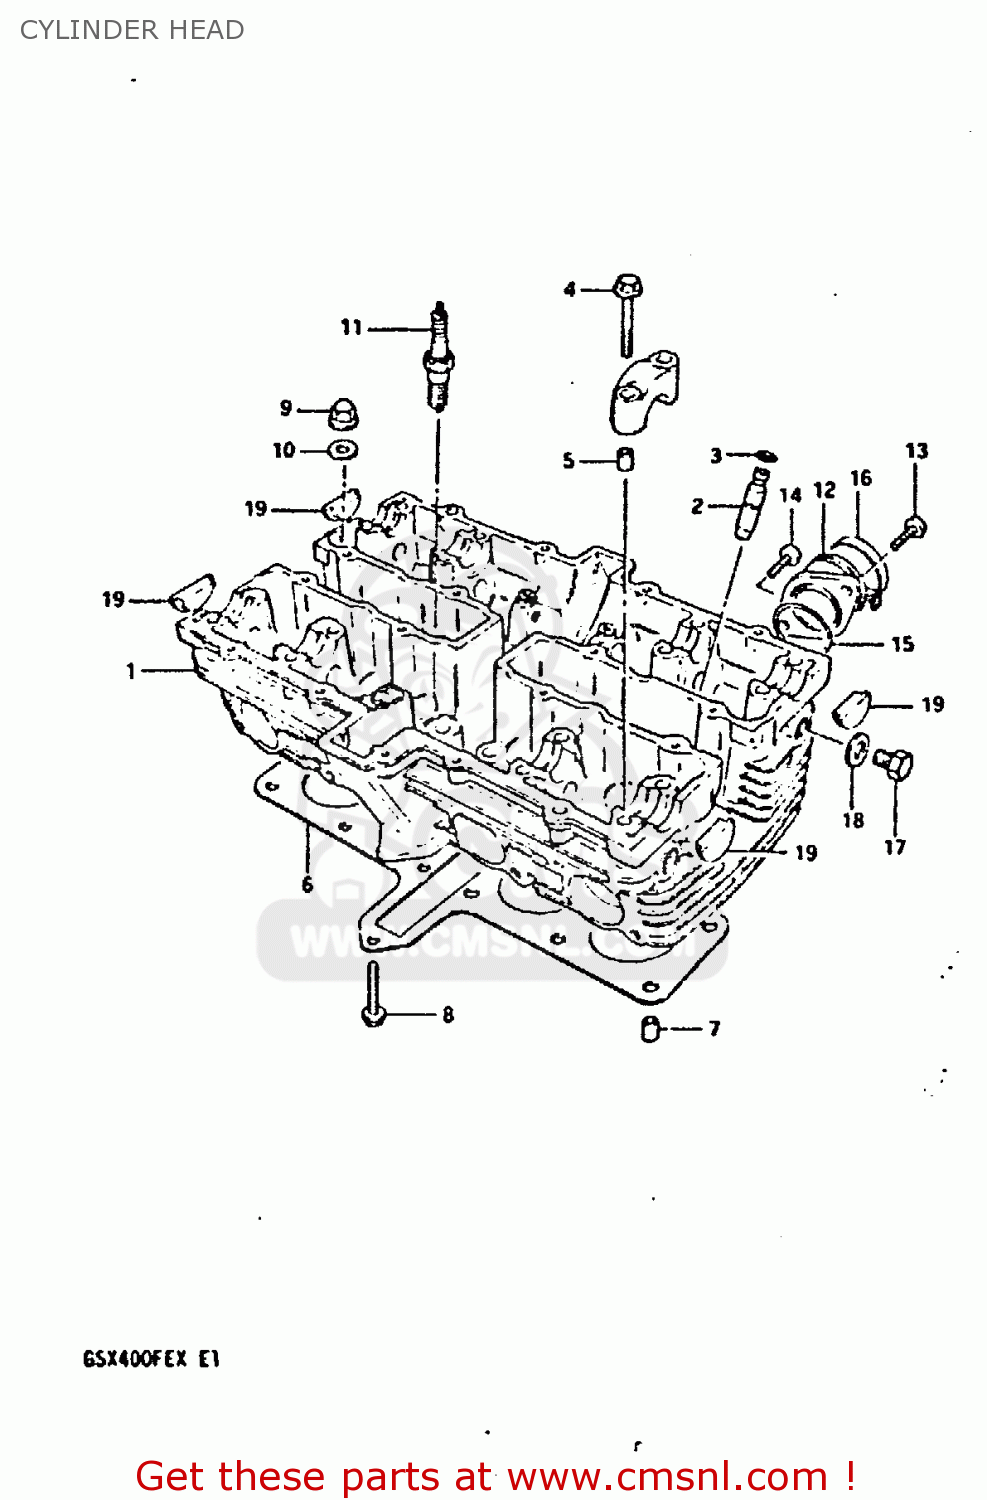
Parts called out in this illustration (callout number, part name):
1	CYLINDER HEAD SET
2	GUIDE, INTAKE VALVE
3	RING,SNAP
4	BOLT(6X39)
5	PIN(6.2X8X11)
6	GASKET
7	PIN
8	BOLT
9	NUT
10	GASKET (NAS)
11	SPARK PLUG DR8ES-L
12	PIPE, INTAKE
13	SCREW
14	SCREW
15	O RING(D:2.4,ID:31.7)
16	CLAMP
17	PLUG (14X12)
18	GASKET(14X19.2X2) (NAS)
19	PLUG
